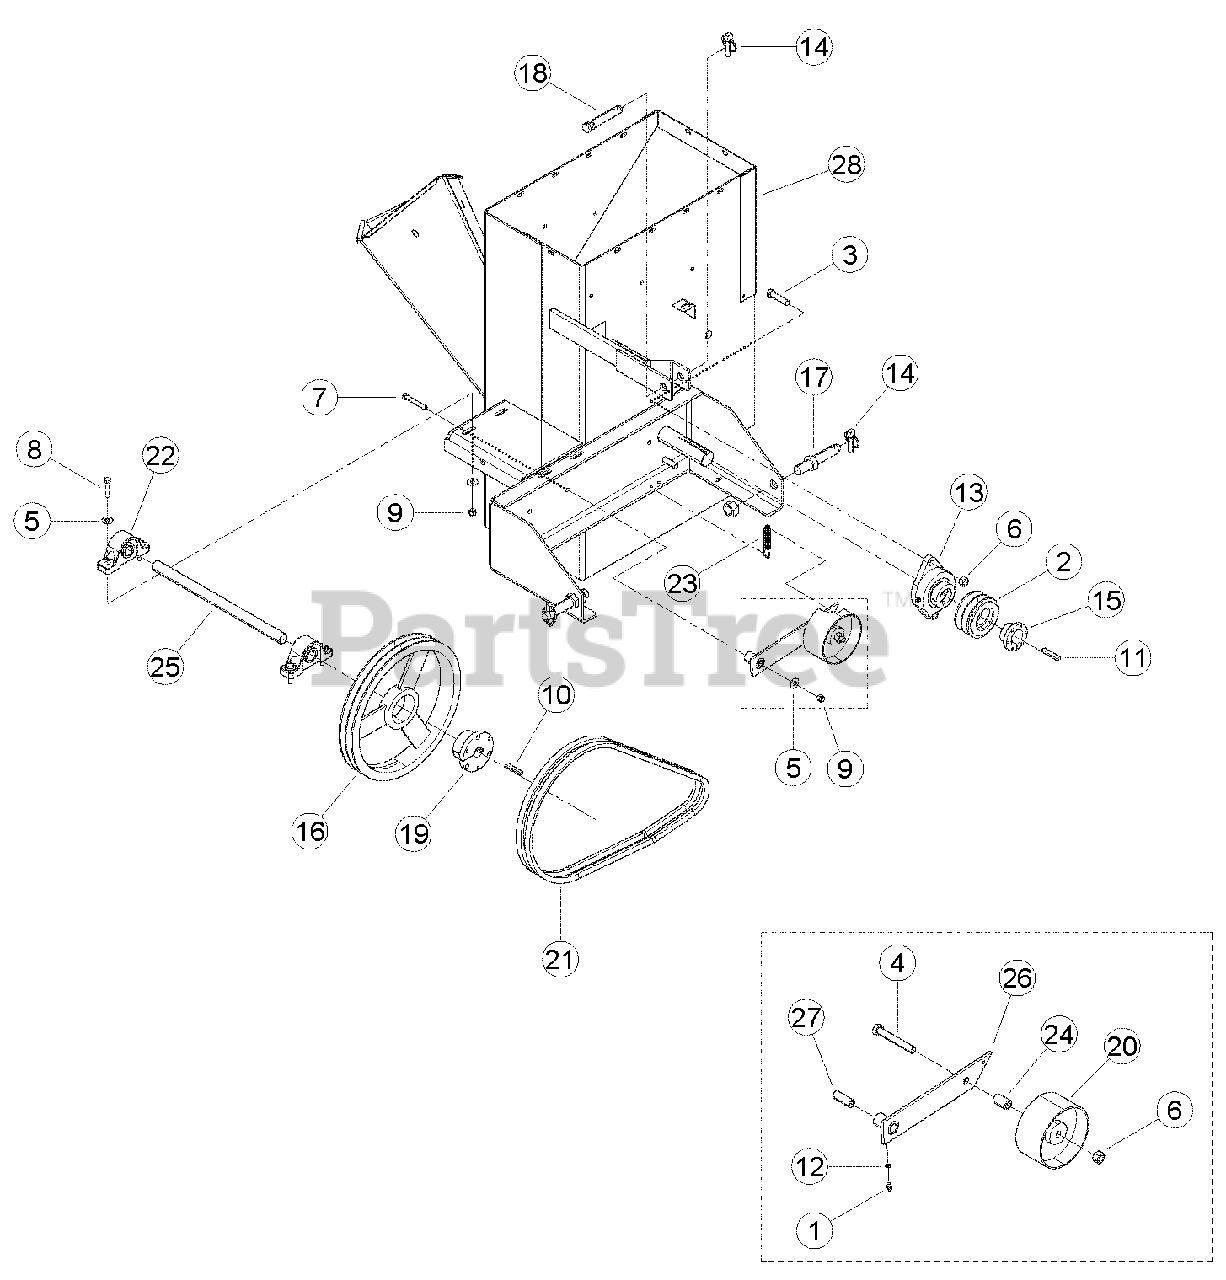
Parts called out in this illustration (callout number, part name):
1	FITTING, 1/4 SELF-TAP GREASE
2	SHEAVE, 2B3.6 SH, QD
3	BOLT, 1/2 X 2 HEX HD GR5 ZP
4	BOLT, 1/2 X 3-1/2 HEX HD GR5 ZP
5	WASHER, 3/8 FLAT ZP
6	NUT, 1/2 CENTERLOCK GRB ZP
7	BOLT, 3/8 X 2-1/2 HEX HD GR5 ZP
8	BOLT, 3/8 X 1-3/4 HEX HD GR5 ZP
9	NUT, 3/8 NE NYLOCK ZP
10	KEY, 1/4 SQUARE X 2 LONG PLAIN
11	KEY, 1/4 X 3/8 X 2
12	WASHER, .254 X .400 X .048 FLAT
13	BEARING, 2 BOLT FLANGE 1-1/2" BORE
14	PIN, 7/16 X 1-3/4 LYNCH
15	BUSHING, SH 1-1/2"
16	SHEAVE, 2B13.6 SK
17	PIN, LIFT ARM 7/8 X 5 LONG
18	PIN, TOP LINK 3/4 X 4-1/2 LONG
19	BUSHING, 1" SK
20	PULLEY, IDLER 5" X 2.50"
21	V BELT BX-56 SINGLE
22	PILLOW BLOCK BEARING 1"
23	SPRING, 3/4"OD EXTENSION
24	SPACER, .75 X 1.18
25	JACKSHAFT, PTO C/S
26	WELDMENT, PTO IDLER ARM
27	SPACER .63 X 1.63
28	WELDMENT, PTO C/S FRAME
